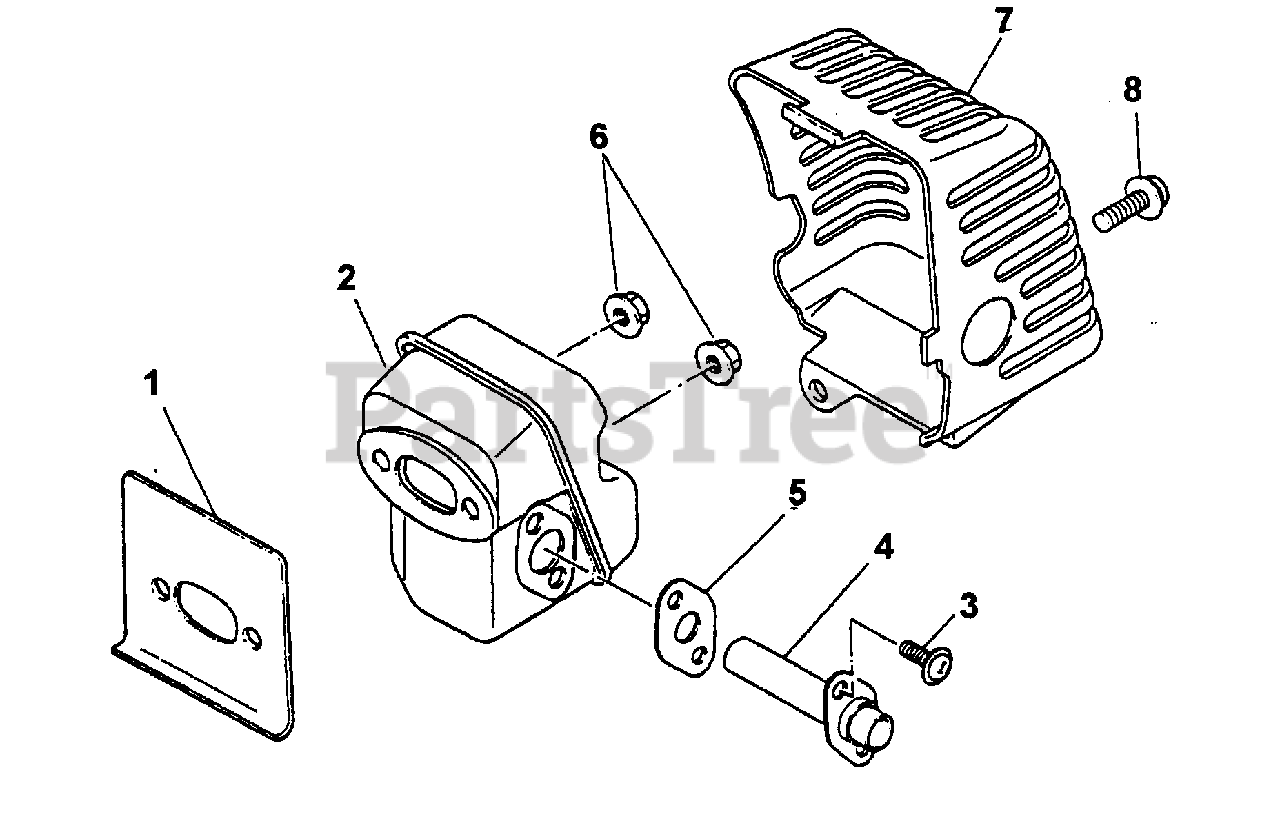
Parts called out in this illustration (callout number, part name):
1	GASKET, MUFFLER
2	MUFFLER ASSEMBLY
3	SCREW & WASHER
4	PIPE, TAIL
5	GASKET, MUFFLER
6	NUT, FLANGE
7	COVER, MUFFLER
8	SCREW & WASHER
